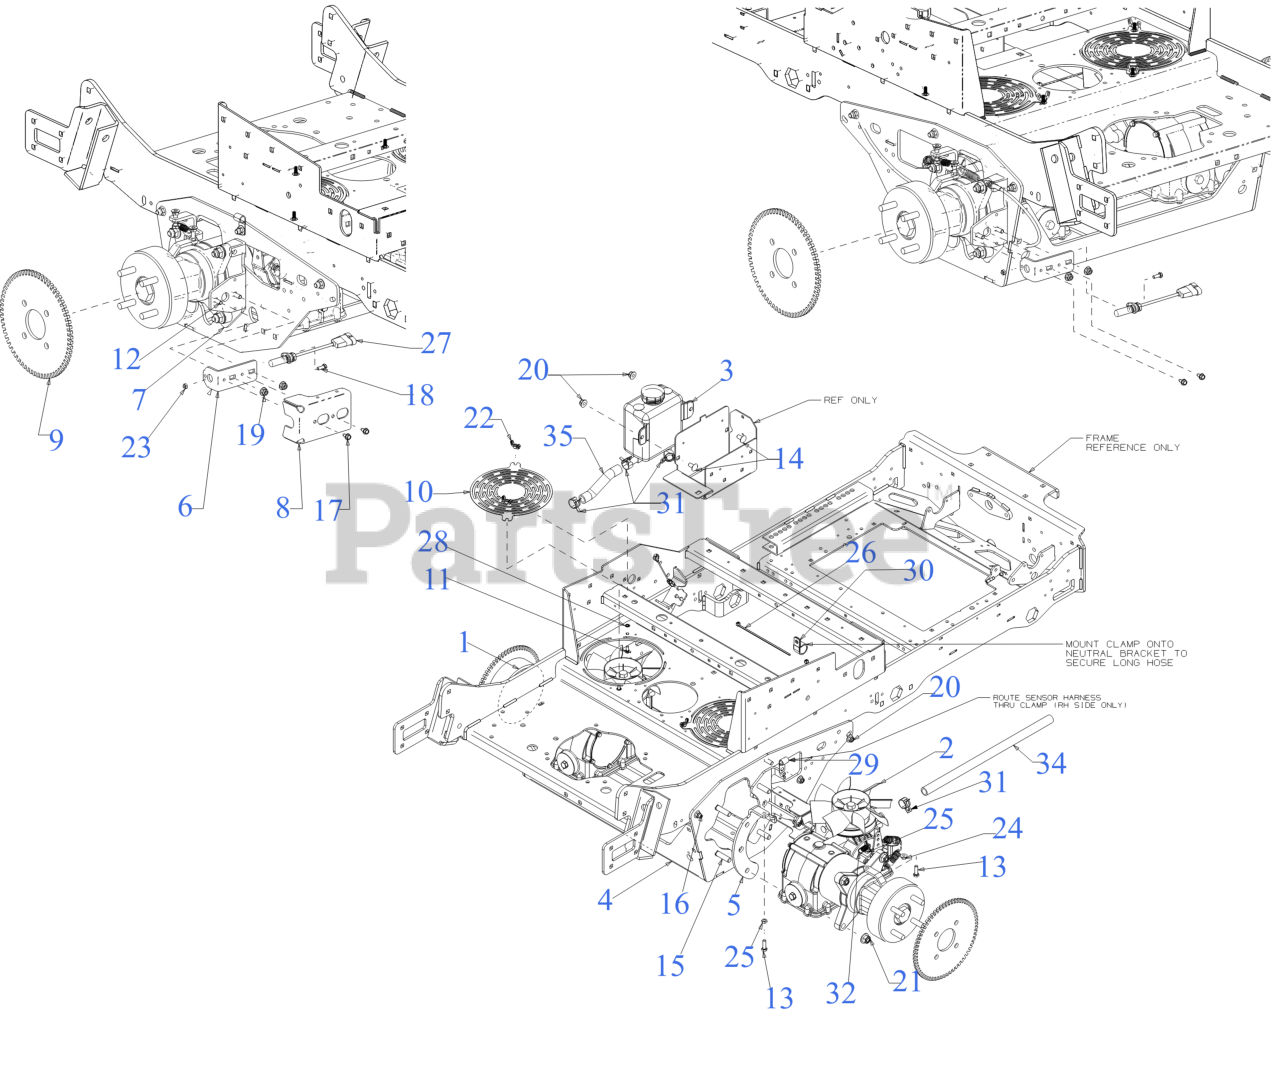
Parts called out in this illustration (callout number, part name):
1	TRANSMISSION ASSEMBLY PARKER (LH)
2	TRANSMISSION ASSEMBLY PARKER (RH)
3	HYDRO TANK ASSEMBLY
4	TRANSMISSION MOUNTING BRACKET
6	WHEEL SENSOR BRACKET
7	BRAKE SENSOR BRACKET
8	WHEEL SENSOR COVER BRACKET
9	WHEEL SENSOR SPACER
10	TRANSMISSION COVER PLATE
11	CARRIAGE BOLT 1/4-20 x .62
12	CARRIAGE BOLT 5/16-18 x 1.00
13	SCREW 5/16-18 x 1.0 GR5
14	CARRIAGE BOLT 3/8-16 x .750 GR5
15	CARRIAGE BOLT 1/2-13 GR5
16	CARRIAGE BOLT 3/8-16 X1.25 GR5
17	SCREW 1/4-20 X.500
19	FLANGE LOCK NUT 5/16-18
22	WING NUT 1/4-20
24	HEX FLANGE NUT
26	7" CABLE TIE
27	WHEEL SPEED SENSOR
28	RETAINER-BOLT .25ID x .50OD
29	J TYPE CLIP
30	HOSE CLAMP 1.0"
31	HOSE CLAMP
32	EXTENSION SPRING .500 OD x 1.71
34	OIL HOSE 5/8 ID x 18.00 LG
